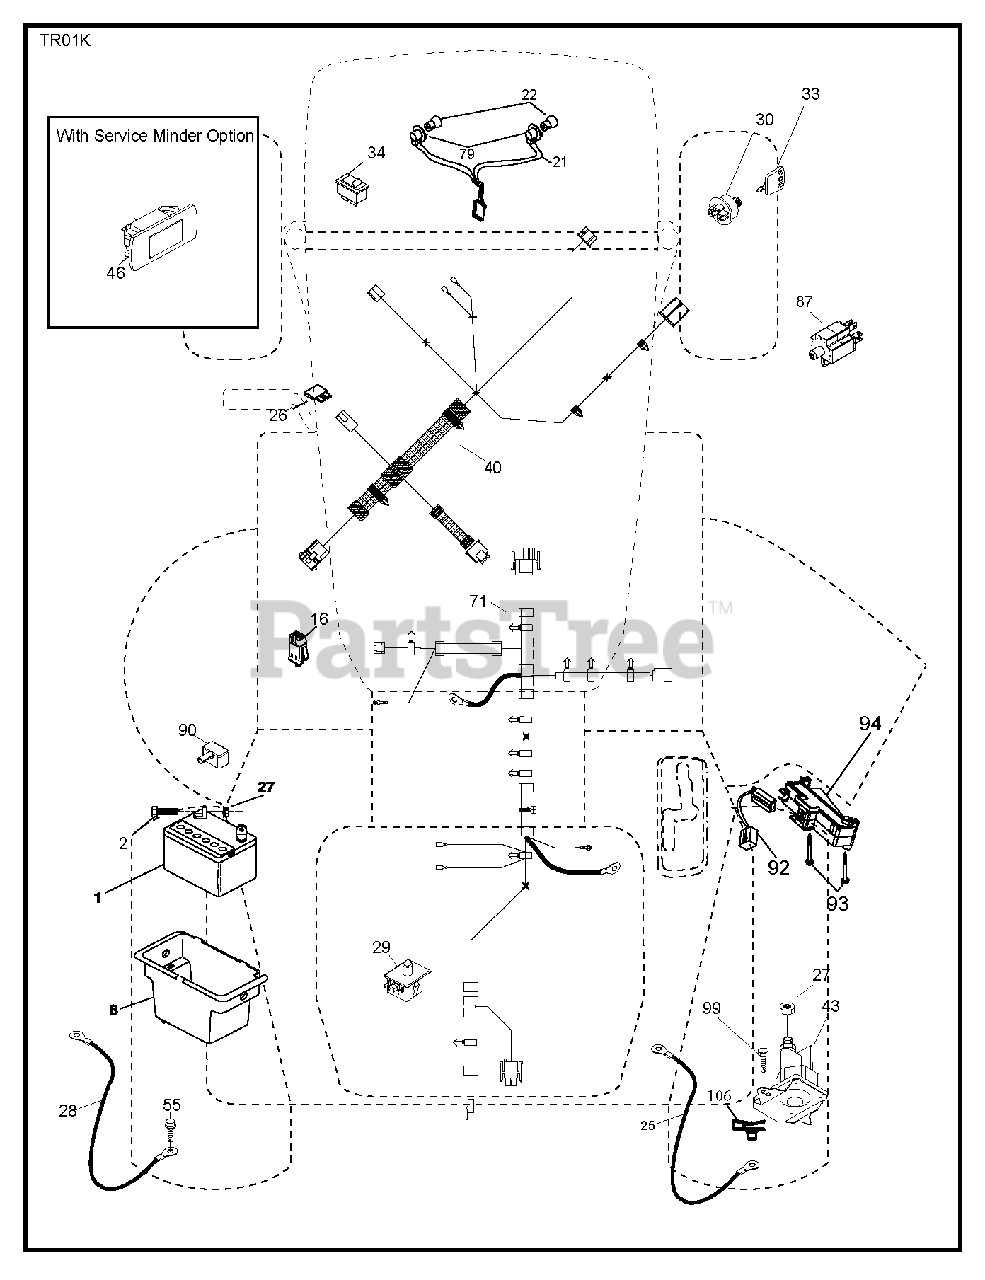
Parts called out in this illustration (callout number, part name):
1	REPL BY 532 12 38-99
2	BOLT.HEX.1/4.X.3/4.DICHROMATE
8	BOX.BATTERY.MNT.REAR.L
16	SWITCH INTERLOOK PUSH-IN
21	HARNESS ASSY LIGHT
22	LIGHTBULB
25	CABLE.BATT.RED.8GA.17
26	FUSE 20AMP
27	NUT
28	CABLE.GROUND.REAR.BATTERY.8G
29	SWITCH.SEAT.DELTA.OPC.
30	SWITCH.IGN.DELTA.W.LGH.ROS
33	KEY.CHAIN.BLISTER.PACK.GEN.INT
34	SWITCH LT
40	HARNESS.TEX.DASH.MAN.REAR BATT
43	SOLENOID.W/BRASS.PLUNGER
55	SCREW 5/16"
71	HARNESS.TEX.CHSSIS.REAR.BATT
79	BULB HOLDER ASM.
87	SWITCH.INTRLCK.CLUTCH.
90	COVER.TERMINAL.BATTERY
92	HARNESS.PIGTAIL.CONSLE
93	SCREW.PLASTITE
94	MODULE.REVERSE.ROS
99	SCREW HEXWSHR 1/4-20X3/4
106	1/4-20 U NUT
